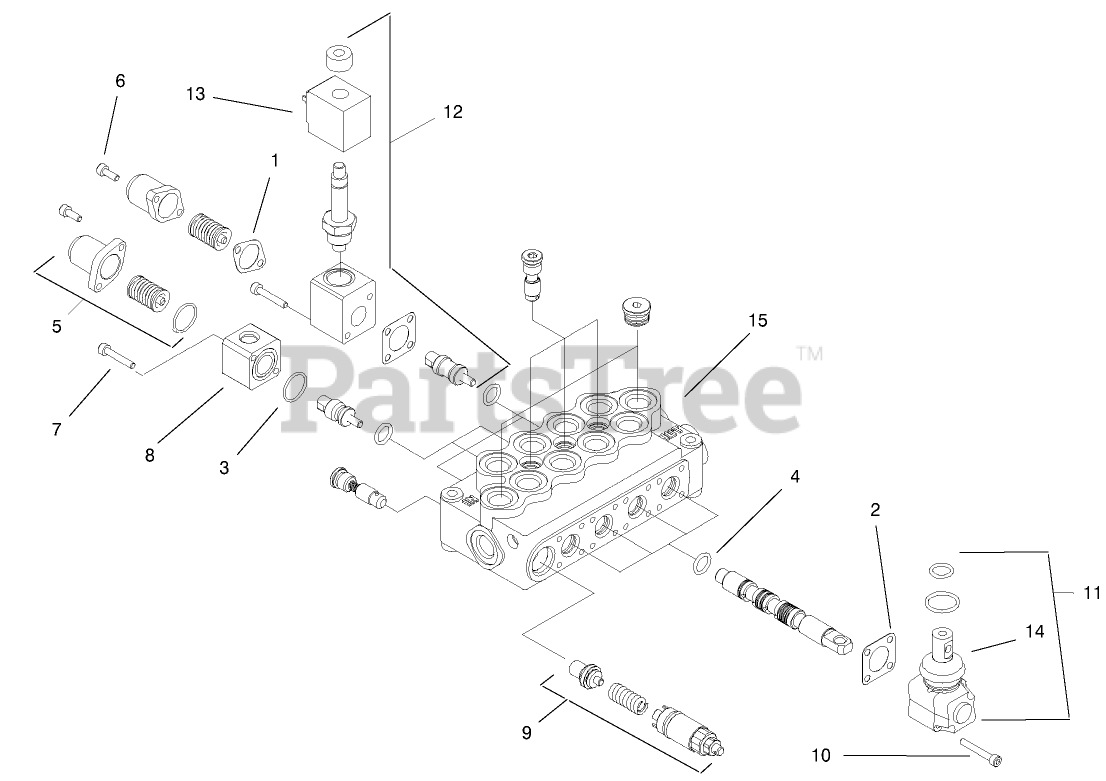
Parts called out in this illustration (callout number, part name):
1	GASKET
2	GASKET
5	STANDARD SPRING KIT
6	SCREW-CAP, END
8	BLOCK-MOUNT, SWITCH
9	VALVE-RELIEF
11	OPERATOR ASM
12	SPOOL LOCK ASM
13	COIL WITH CONNECTOR
15	Valve-Hyd. 4 spool (Incl. Ref.# 2, 4-6, 9-11, 14)
